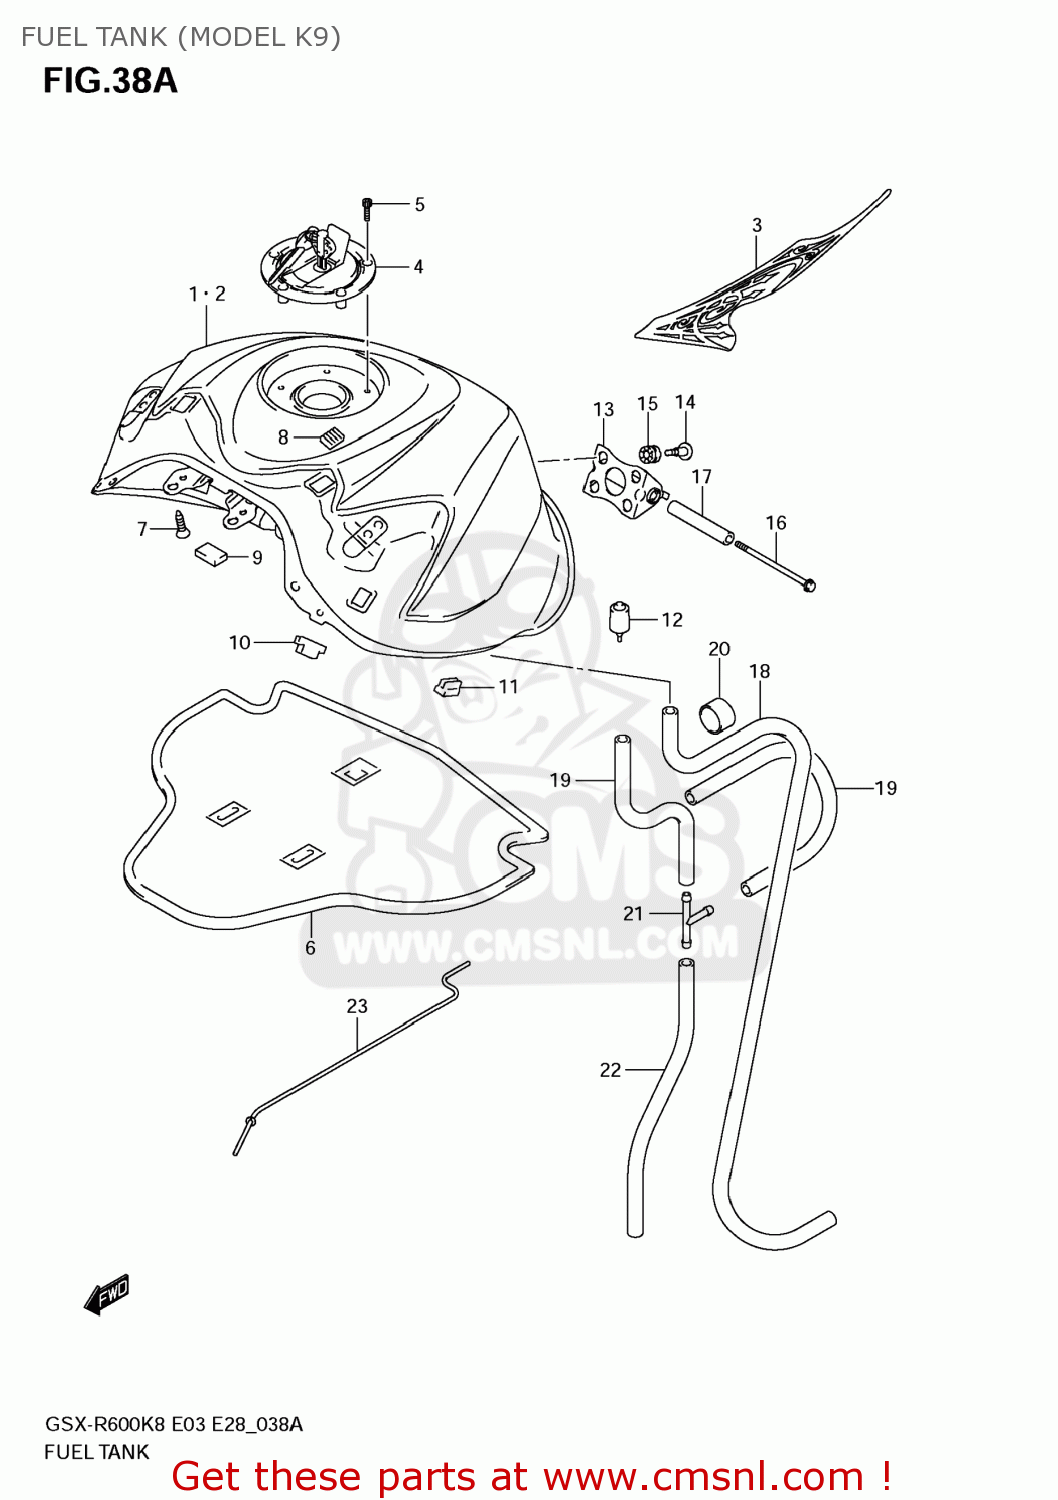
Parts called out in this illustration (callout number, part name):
1	TANK ASSY,FUEL
2	TANK ASSY,FUEL(BLACK)
3	TAPE SET,FUEL TANK
4	CAP SET,FUEL TANK
5	BOLT(5X20)
6	SHIELD,FUEL TANK HEAT
7	SCREW(6X10)
8	FASTENER
9	CUSHION
10	CUSHION,FUEL TANK SIDE
11	CUSHION,FUEL TANK COVER
12	CUSHION,FUEL TANK RR
13	BRACKET,FUEL TANK NO.1
14	SCREW,FUEL TANK RR BRACKET
15	CUSHION
16	BOLT(6X110)
17	SPACER,FUEL TANK RR
18	HOSE,TANK WATER DRAIN
19	HOSE,TANK BREA
20	HOSE(12X16X600)
21	JOINT,3 WAY
22	HOSE(5X8.2X2000)
23	STAY,FUEL TANK
